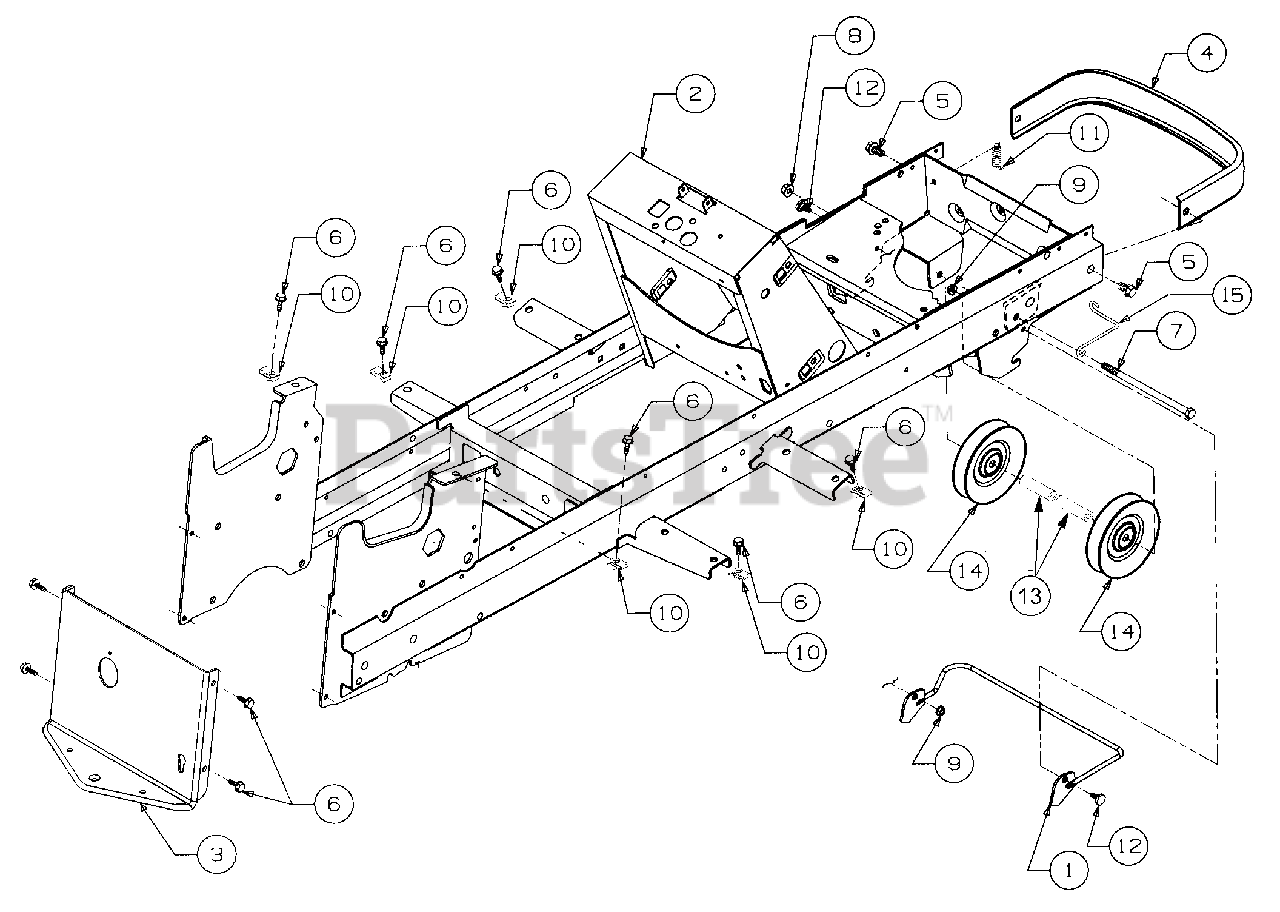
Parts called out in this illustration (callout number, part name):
6	Screw, Hex Wsh Hd Tap 5/16-18 x .75
7	Screw, Hex Cap, 3/8-16 x 7.0
8	Nut, Hex Flange Lock, 3/8-16
9	Nut, Hex Flange Lock, 1/4-20
10	U-Nut, 5/16-18
11	Spring, Latch
12	Bolt, Shoulder
13	Spacer, Idler, .411 x .720 x 2.19
14	Pulley, Idler
15	Belt Guide
